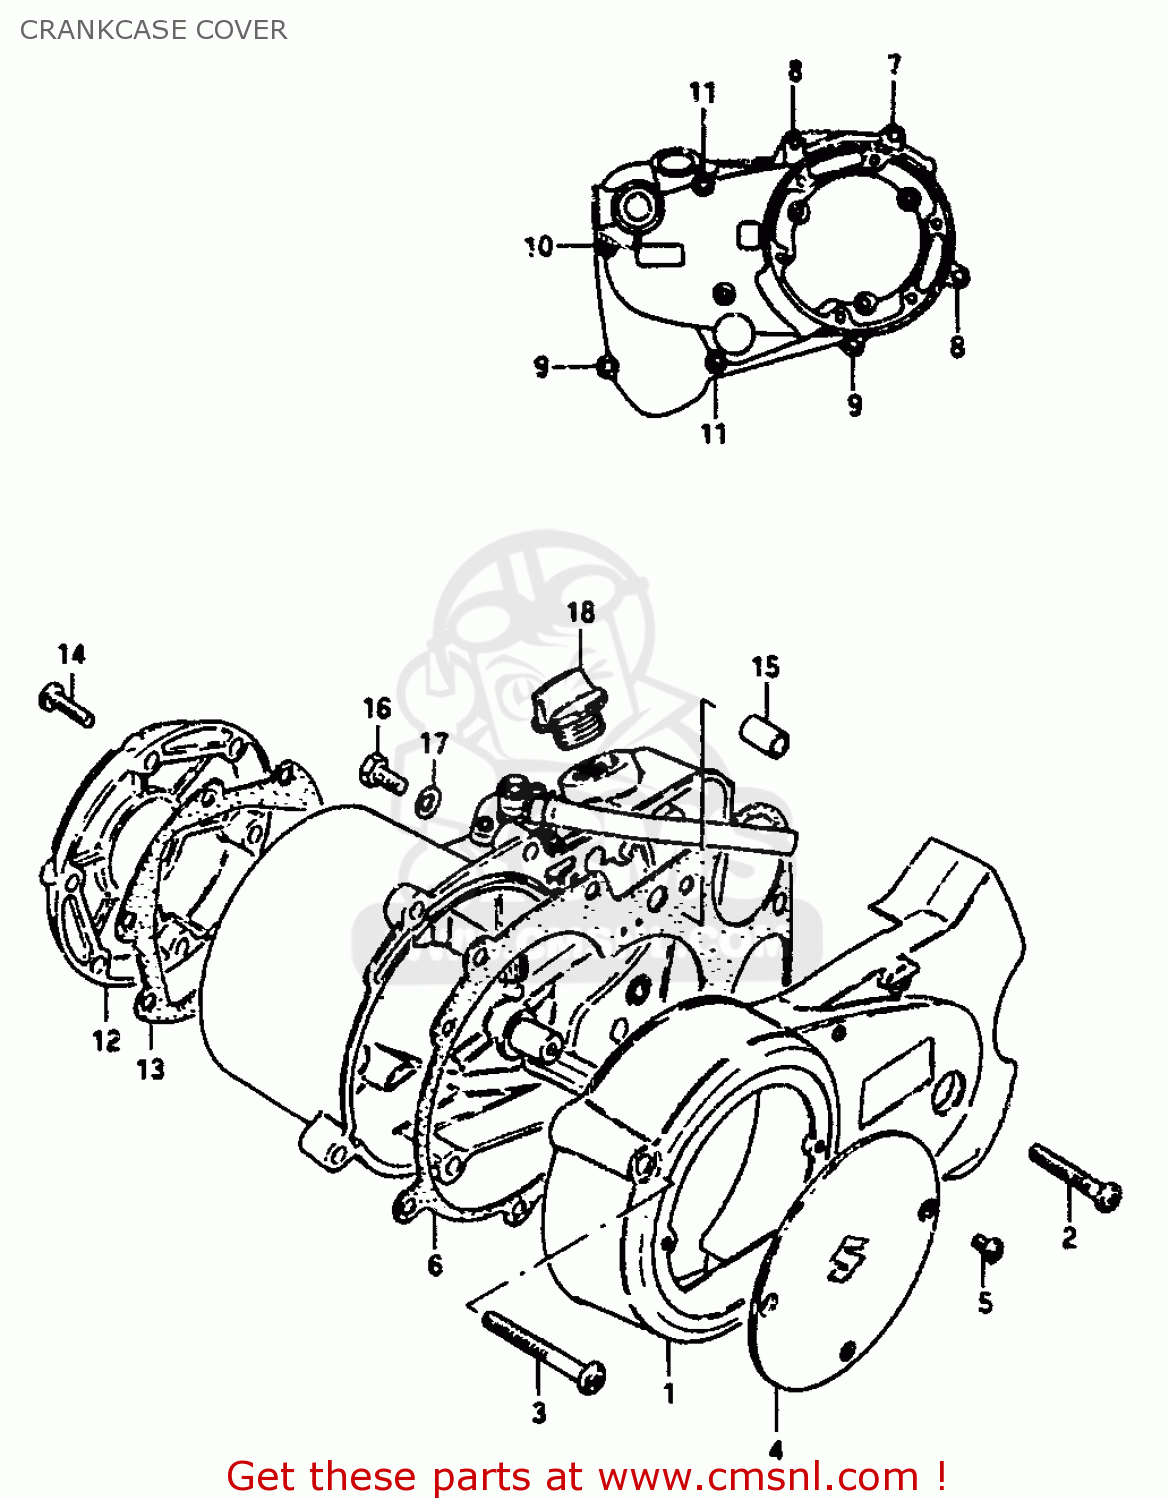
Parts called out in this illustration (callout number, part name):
1	COVER,MAGNETO
2	SCREW
3	SCREW
4	CAP,MAGNETO INSPECTION
5	SCREW
6	GASKET,CLUTCH COVER (MCA)
7	SCREW
8	SCREW
9	SCREW
10	SCREW
11	SCREW
12	CAP,CLUTCH RELEASE ADJUST
13	GASKET,CLUTCH RELEASE ADJUSTER CAP (NAS)
14	SCREW
15	PIN
16	SCREW(6X10)
17	GASKET(6.2X11X1) (NAS)
18	PLUG SET
